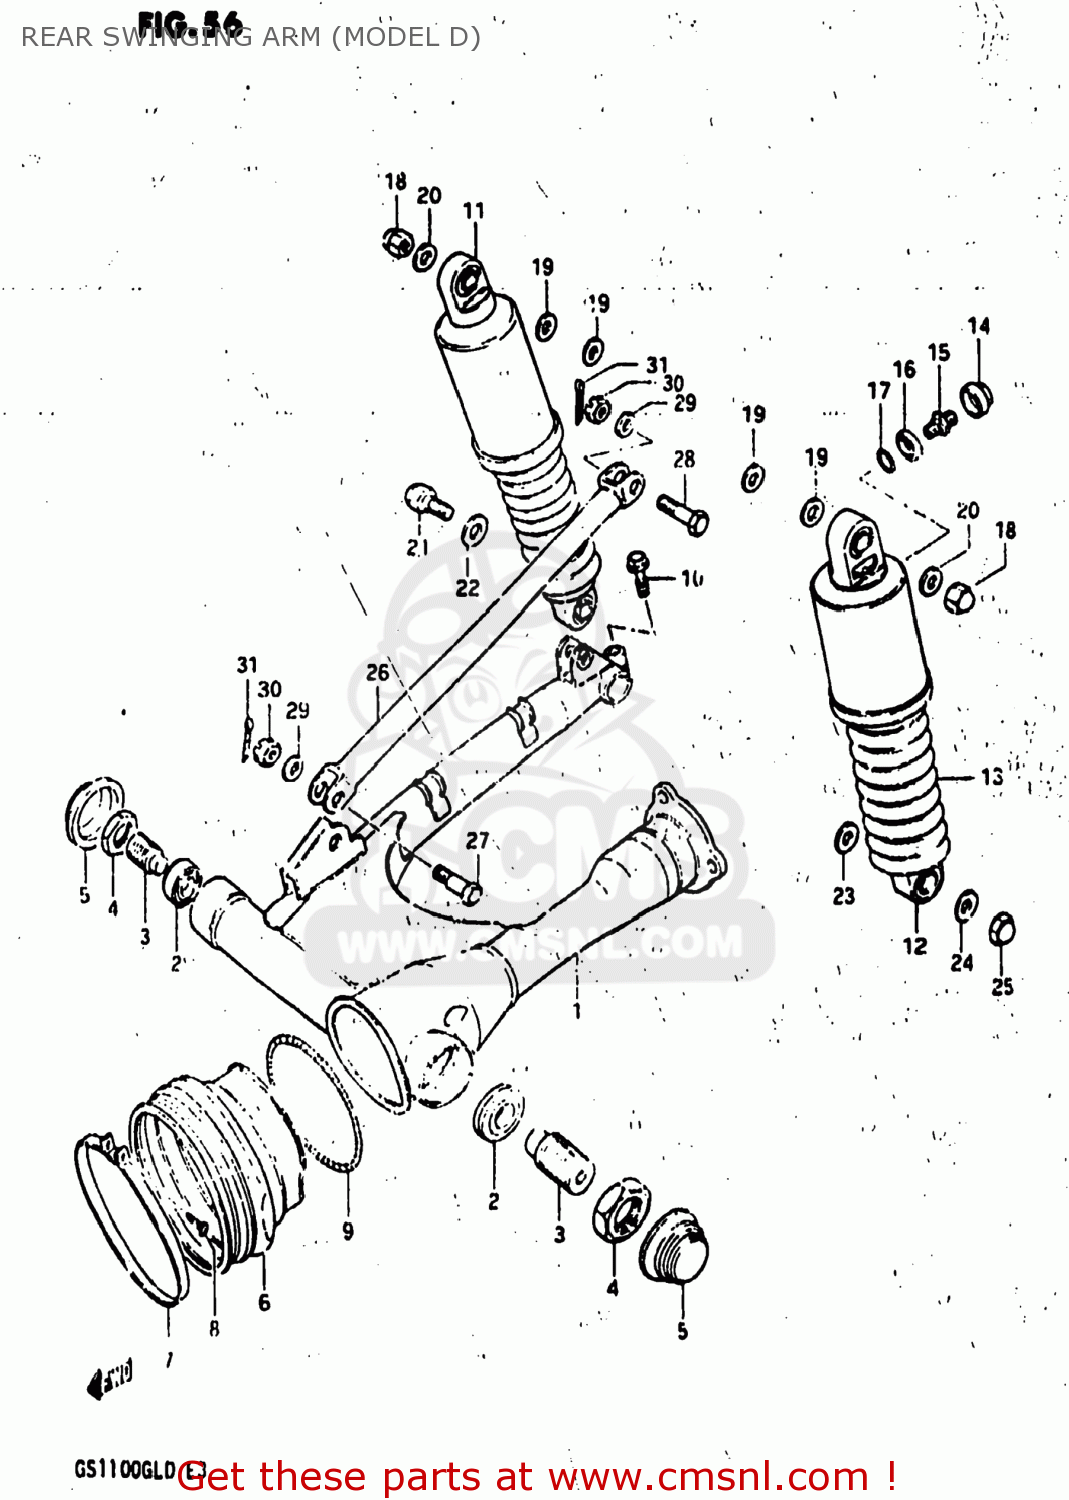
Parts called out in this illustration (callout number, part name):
1	SWING ARM SET,REAR (B
2	BEARING(17X40X13.25)
3	BOLT,REAR SWING ARM PIVOT
4	NUT
5	CAP,REAR SWING ARM PIVOT
6	BOOT,PROPELLER SHAFT
7	CLAMP
8	SCREW 4X25
9	SPRING,PROPELLER SHAFT
10	BOLT
11	ABSORBER ASSEMBLY,REAR SHOCK
12	ABSORBER ASSEMBLY,REAR SHOCK
13	BOOT,RR SHOCK
14	CAP,VALVE
15	VALVE,FRONT FORK AIR
16	SPACER,REAR SHOCK ABSORBER
17	O RING,RR SHOCK
18	NUT
19	WASHER
20	WASHER
21	BOLT 12X33
22	WASHER (12.5X24X1.6)
23	WASHER
24	WASHER
25	NUT, LOWER LH
26	TORQUE LINK,REAR
27	BOLT
28	BOLT(10X39)
29	WASHER
30	NUT
31	PIN 20X20
